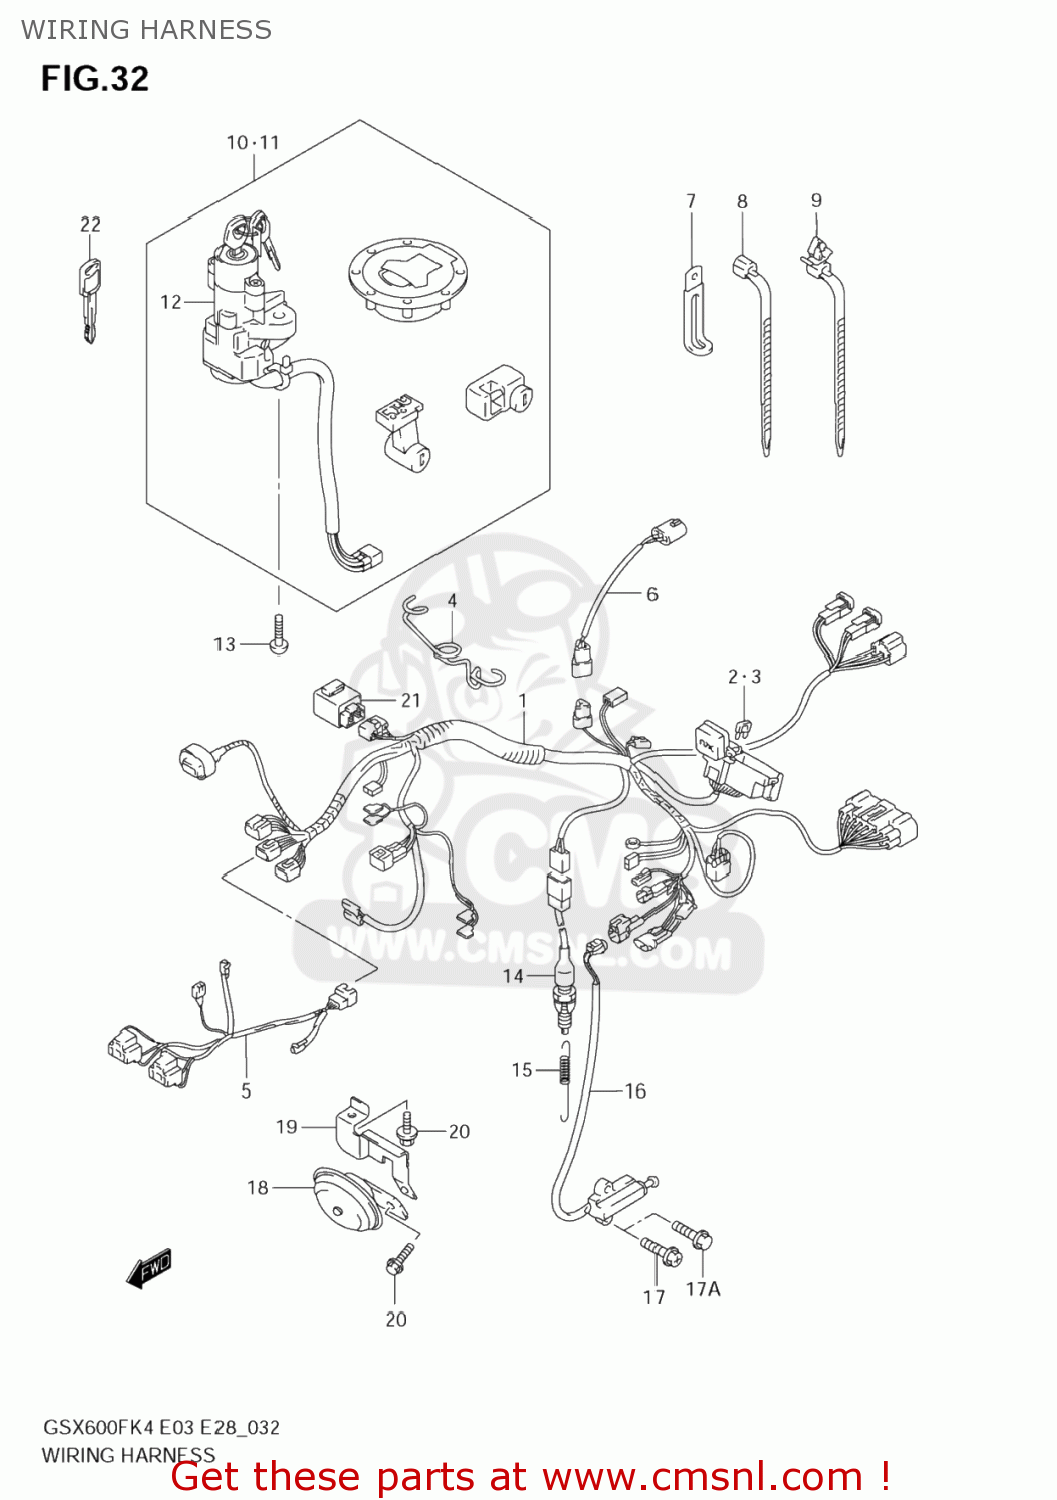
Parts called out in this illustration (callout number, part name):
1	HARNESS,WIRING
2	FUSE(10A)
3	FUSE(15A)
4	GUIDE,WIRING HARNESS
5	HARNESS,WIRING NO.2
6	WIRE,LEAD
7	CLAMP(L:135)
8	CLAMP(L:95)
9	CLAMP(L:90)
10	LOCK SET
11	LOCK SET
12	LOCK ASSY,STEE
13	BOLT(8X20)
14	SWITCH ASSY,STOP LAMP
15	SPRING
16	SWITCH ASSY,SIDE STAND
17	SCREW
17A	BOLT
18	HORN ASSY
19	BRACKET,HORN
20	BOLT
21	CONTROLLER ASSY,FAN MOTOR
22	KEY,BLANK
